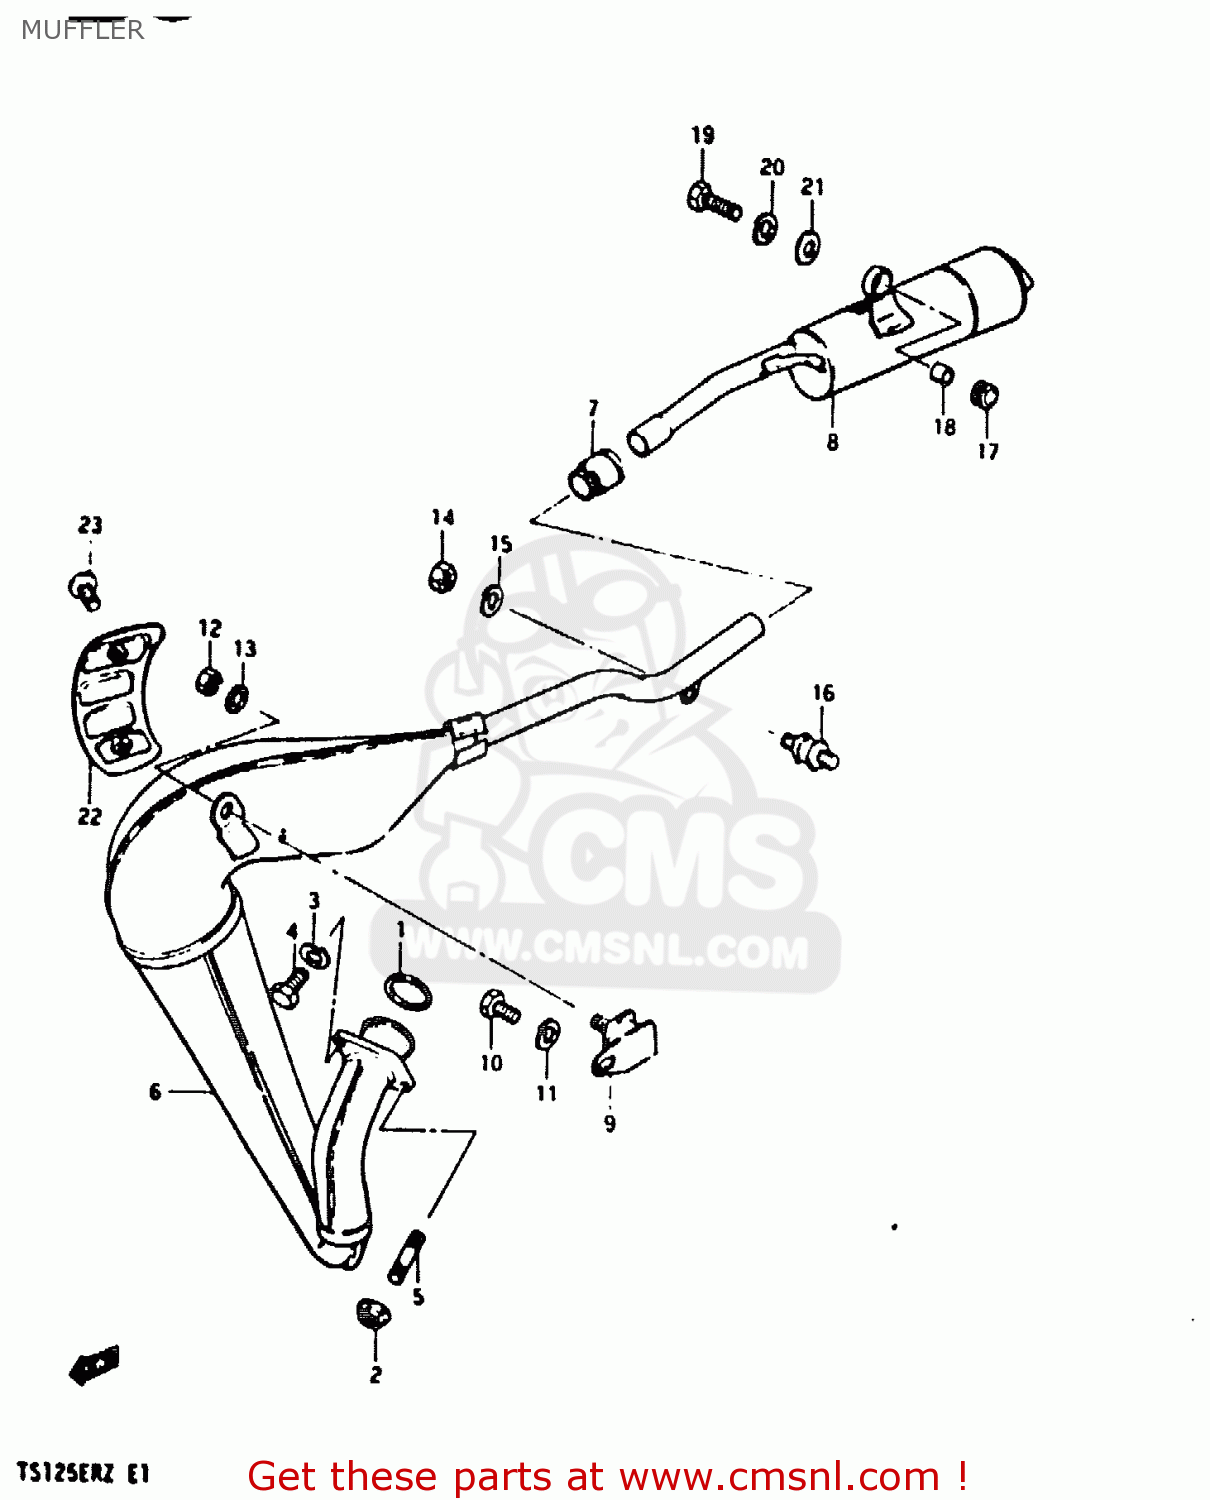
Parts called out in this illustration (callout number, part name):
1	GASKET,EXHAUST PIPE (NAS)
2	NUT 8MM
3	LOCK WASHER
4	BOLT
5	STUD 8X20
6	MUFFLER, 1ST
7	CONNECTOR,MUFFLER
8	MUFFLER, 2ND
9	DAMPER,MUFFLER SUPPORT
10	BOLT
11	LOCK WASHER
12	NUT 8MM
13	WASHER
14	NUT 8MM
15	LOCK WASHER
16	BUSH
17	CUSHION
18	SPACER (8.6X12X17.5)
19	BOLT
20	LOCK WASHER
21	WASHER (8.5X29X1.6)
22	COVER,MUFFLER
23	SCREW, PLATE
